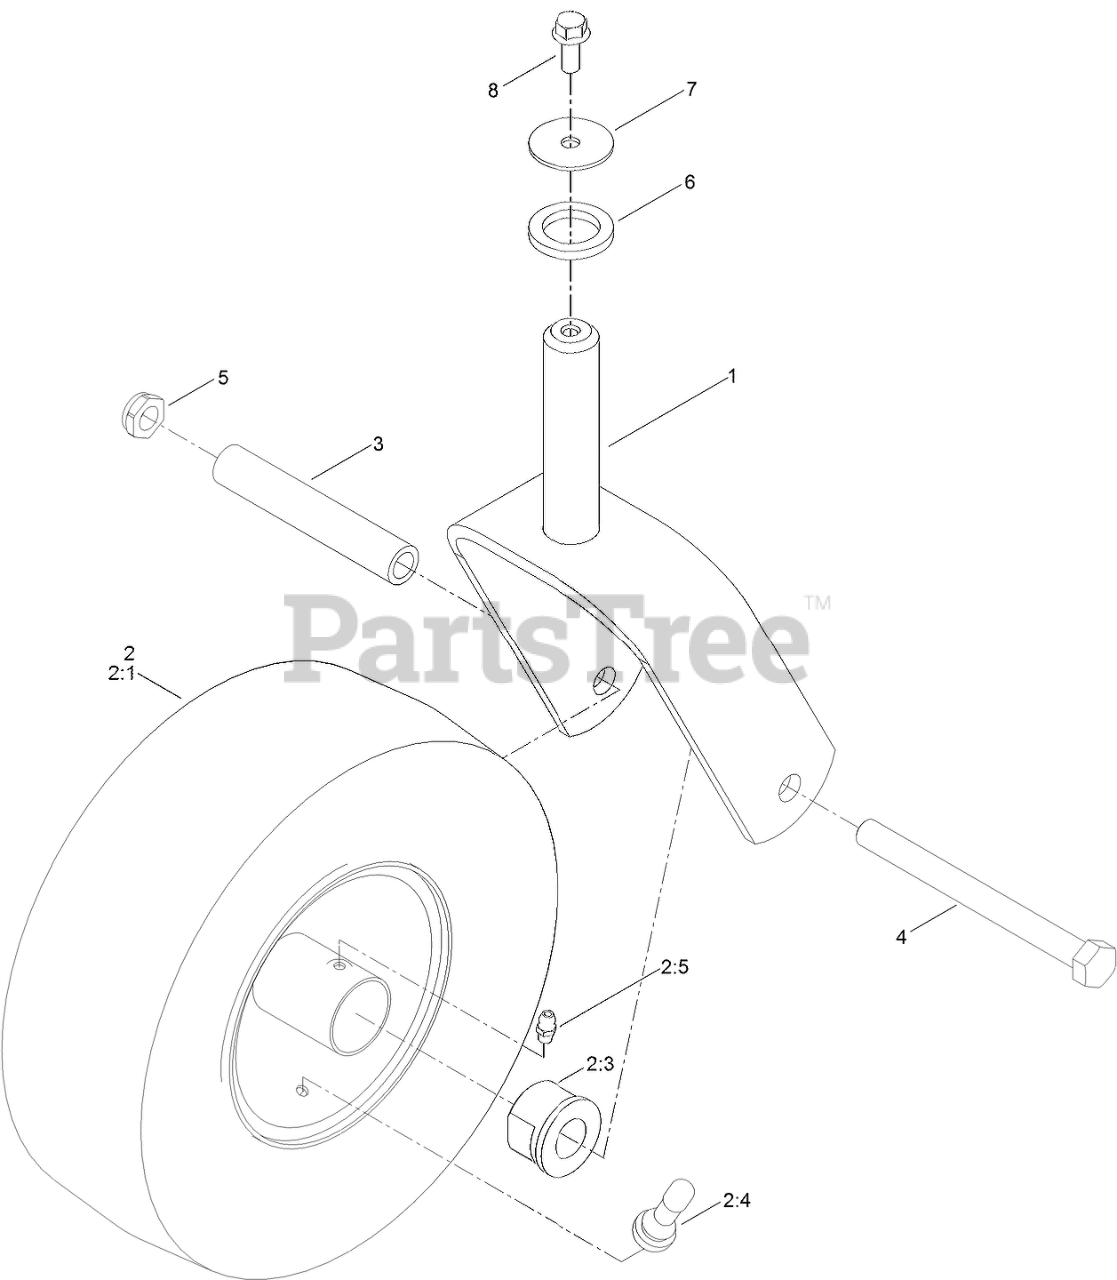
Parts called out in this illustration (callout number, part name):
1	CASTER FORK ASM
2	CASTER WHEEL ASM
2:3	BUSHING-FLANGE
2:5	FITTING-GREASE
2:6	TUBE-INNER
3	BUSHING-SPANNER
4	SCREW-HH
5	NUT-LOCK, NI
6	WASHER-THRUST
7	WASHER-FLAT
8	SCREW-HHF
